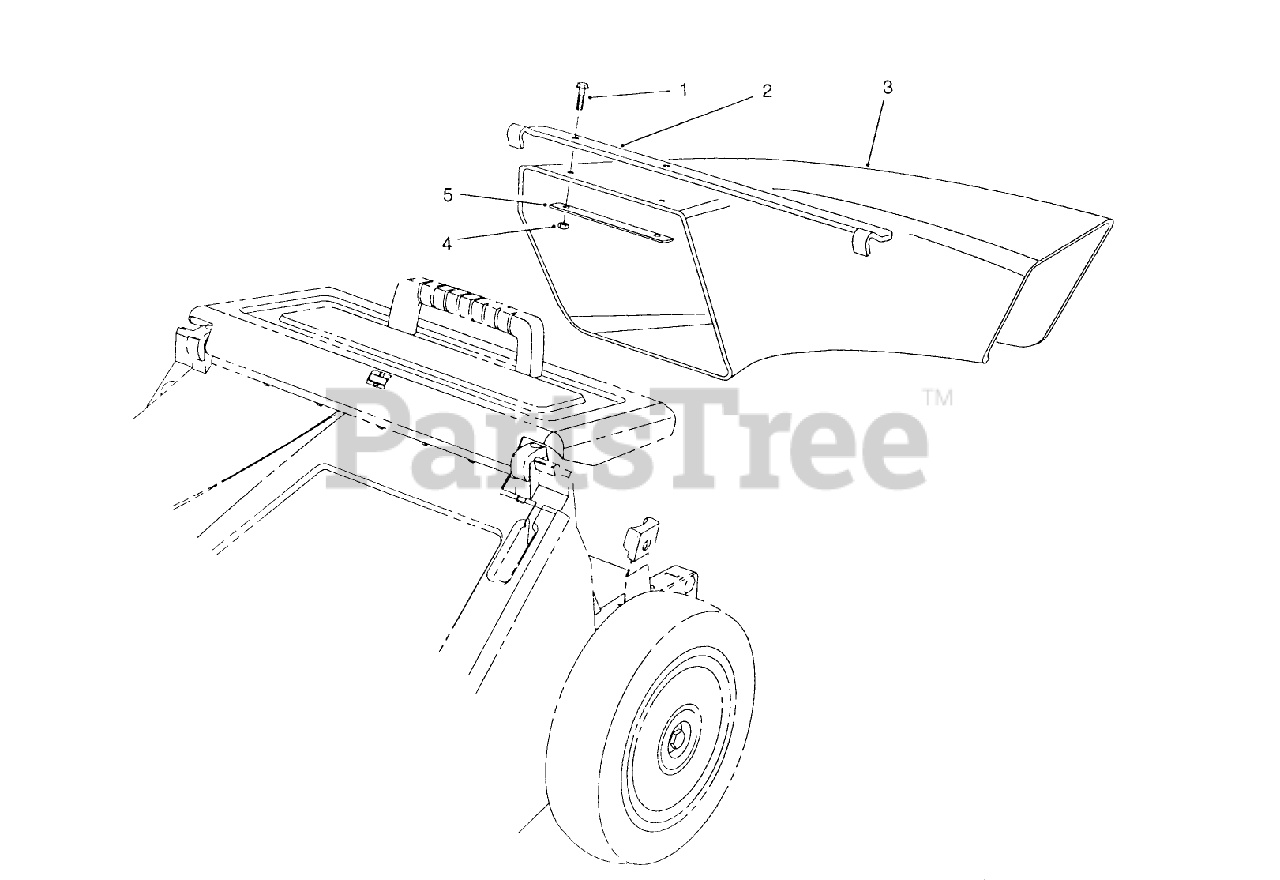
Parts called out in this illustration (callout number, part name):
1	SCREW-HWH
2	CHUTE HANGER BRACKET*
4	NUT-LOCK, NI
